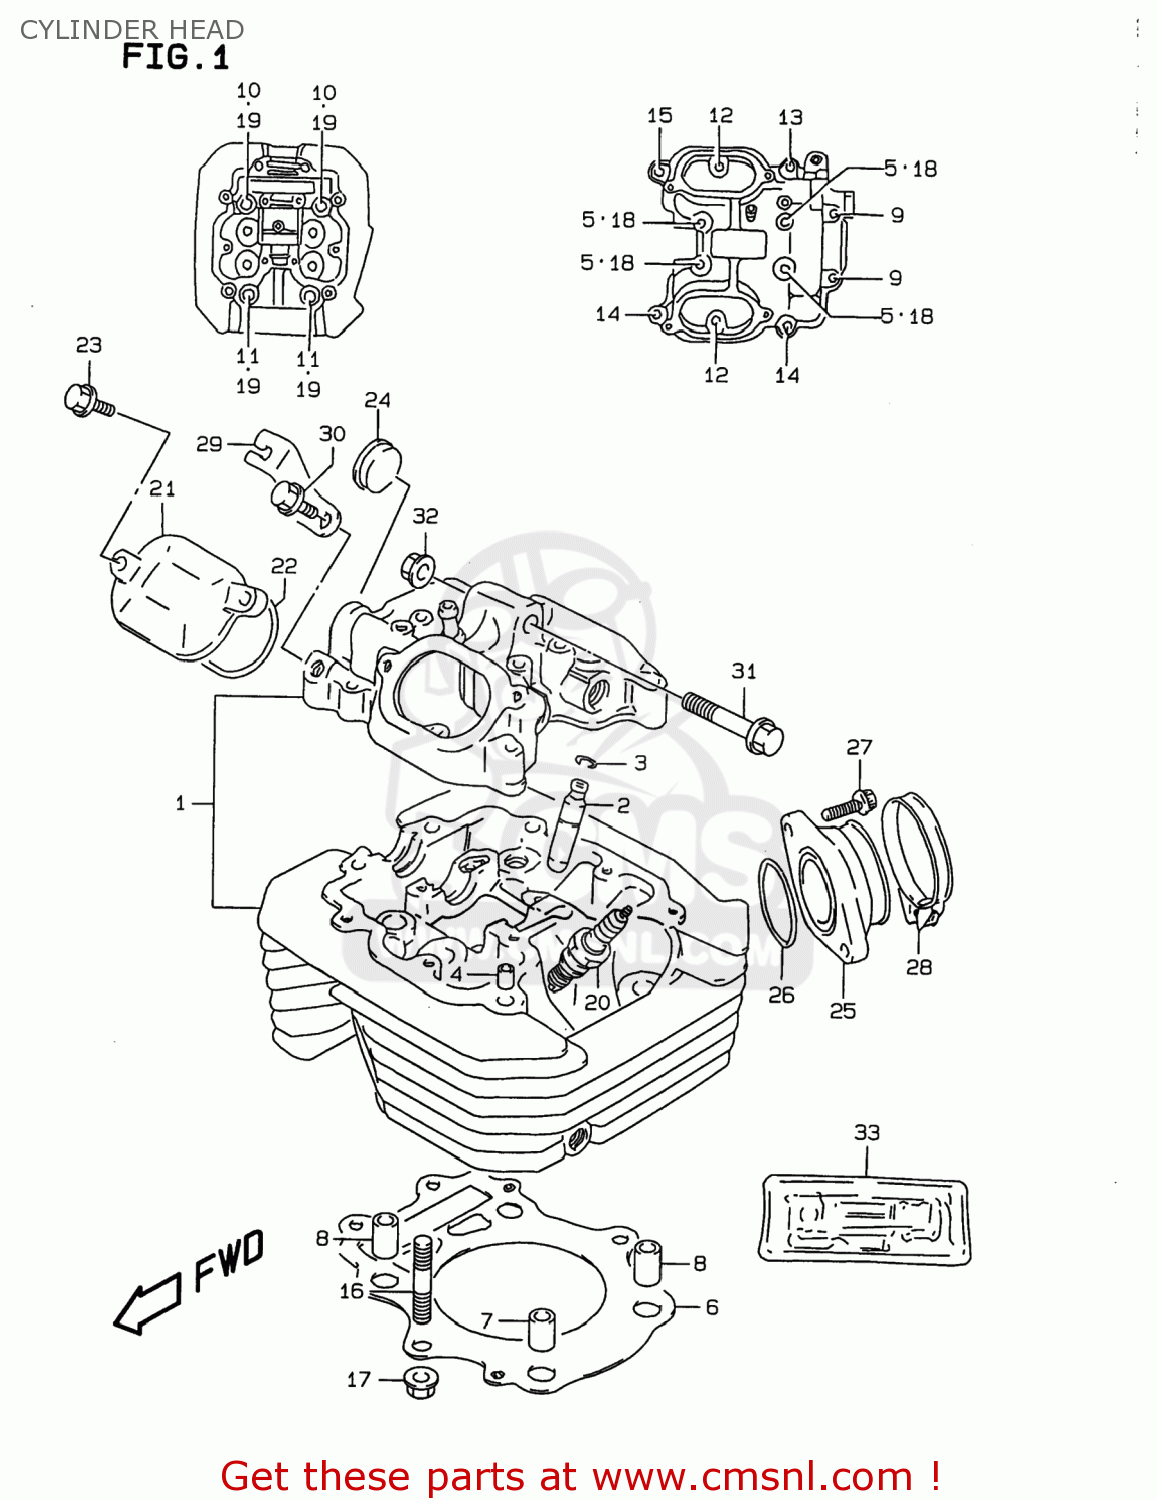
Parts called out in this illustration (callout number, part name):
1	HEAD ASSY,CYLINDER
2	GUIDE,VALVE
3	RING,SNAP
4	PIN(6.2X8X11)
5	BOLT(6X55)
6	GASKET,CYLINDER HEAD (NAS)
7	PIN
8	PIN(10.4X13X22)
9	BOLT(6X115)
10	BOLT(10X180)
11	BOLT(10X155)
12	BOLT
13	BOLT
14	BOLT(6X35)
15	BOLT(6X39)
16	BOLT,STUD
17	NUT
18	GASKET(5.8X13X1.2) (NAS)
19	WASHER (10.5X22X2.3)
20	PLUG,SPARK(CR9EK)
21	CAP,INSPECTION
22	O RING,INSPECTION CAP
23	BOLT
24	PLUG,OD:30
25	PIPE ASSY,INTAKE
26	O RING(D:2.4,ID:39.7)
27	BOLT
28	CLAMP
29	LEVER,DECOMP SHAFT RH
30	BOLT
31	BOLT(8X65)
32	NUT
33	GASKET SET (NAS)
